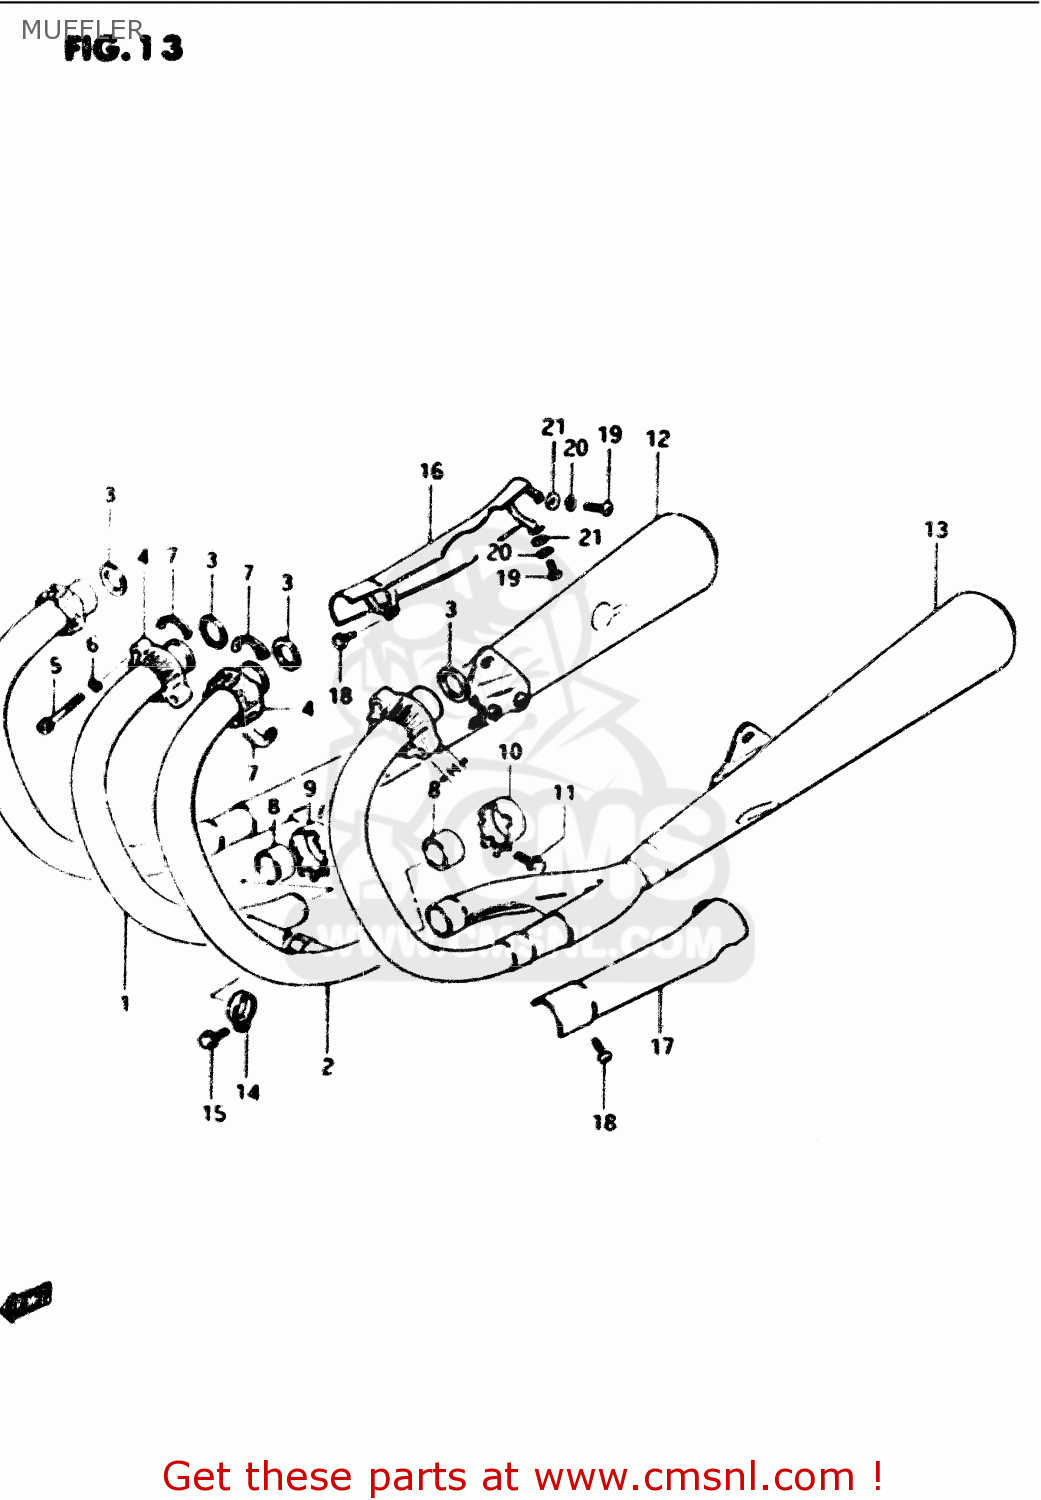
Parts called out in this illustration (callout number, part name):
1	PIPE,EXHAUST,CENTER,RIGHT
2	PIPE,EXHAUST,CENTER,LEFT
3	GASKET,EXHAUST PIPE (NAS)
4	CLAMP(H:21)
5	BOLT
6	LOCK WASHER
7	PLATE,EXHAUST P
8	CONNECTOR,MUFFLER
9	CLAMP,MUFFLER CONNECTOR,R
10	CLAMP,MUFFLER CONNECTOR,L
11	BOLT
12	MUFFLER, RH
13	MUFFLER, LH
14	CLAMP
15	BOLT
16	COVER,MUFFLER,RIGHT
17	COVER,MUFFLER,LEFT
18	SCREW
19	SCREW
20	WASHER,LOCK
21	WASHER
